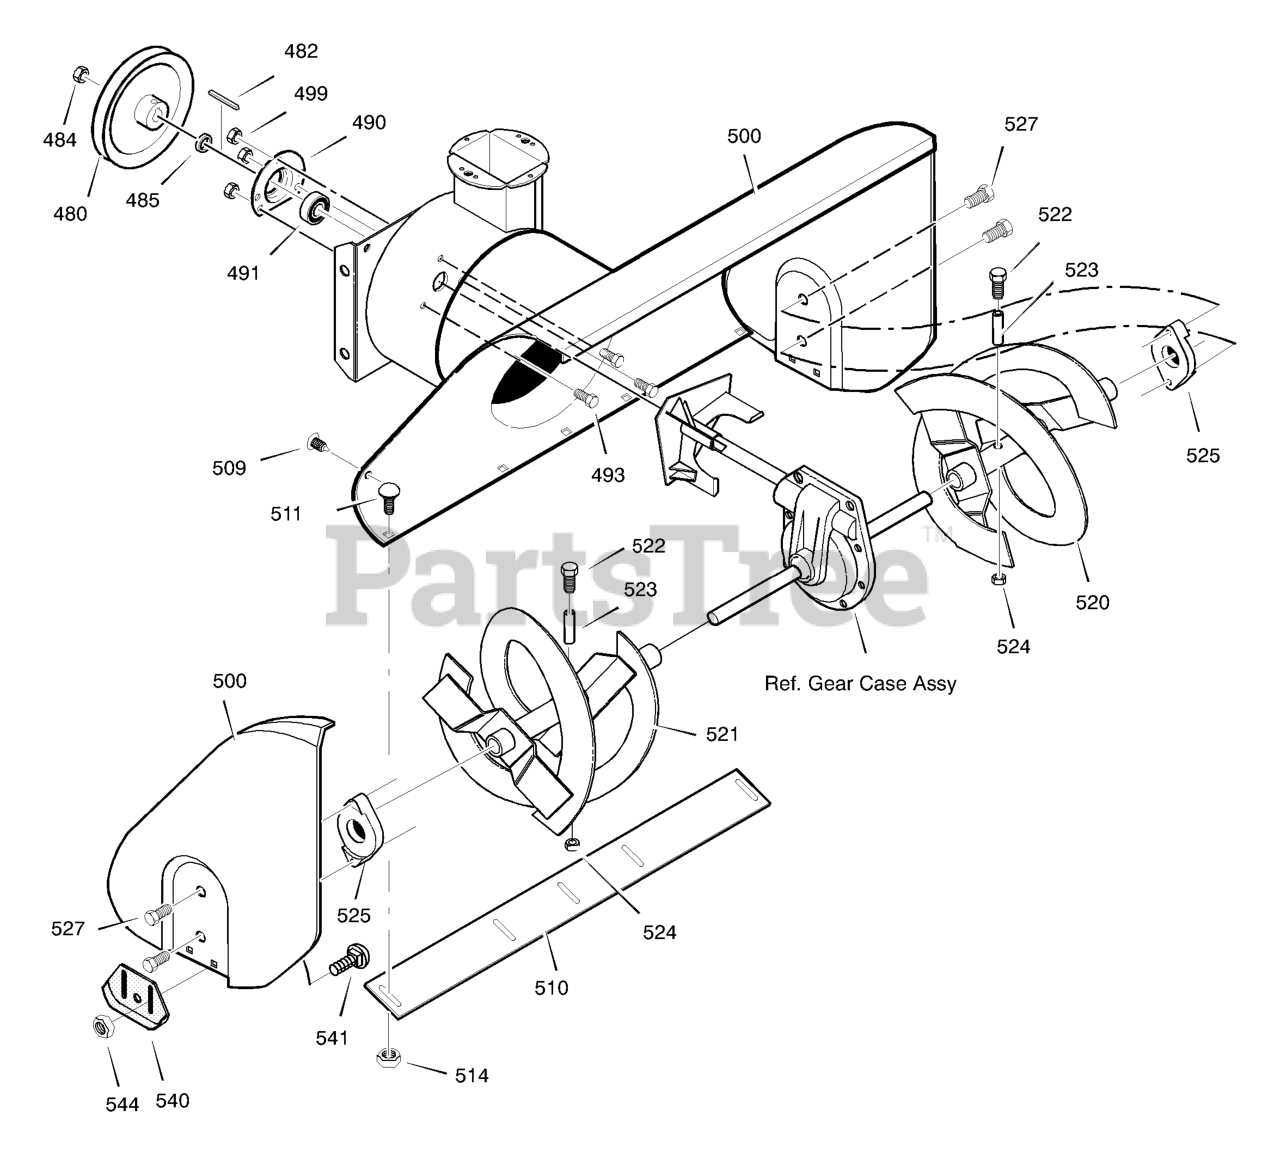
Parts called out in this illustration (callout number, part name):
480	PULLEY, 4L 8.40 OD
482	KEY, SQUARE 3/16 X 3/4
484	NUT, 1/2-20
485	SPACER, FRICTION PULLEY
490	RETAINER, BALL BRNG
491	BEARING, BALL
493	BOLT, HEX 5/16-18X .50
499	NUT, 5/16-18 HEXWDFLLK
500	HOUSING, ASSY
509	PLUG, CHRISTMAS TREE
510	BLADE, SCRAPER 29"
511	BOLT, 5/16-18X.75
514	NUT, 5/16-18
520	AUGER, ASSY, LH
521	AUGER, ASSY, RH
522	BOLT, 1/4-20 x 1.75
523	SPACER, SLEEVE
524	NUT, 1/4-20
525	BEARING,FLANGE
527	SCREW, 5/16-18 x 0.75
540	SKID, HEIGHT ADJUST
541	BOLT, 5/16-18 X .75
544	NUT, 5/16-18
